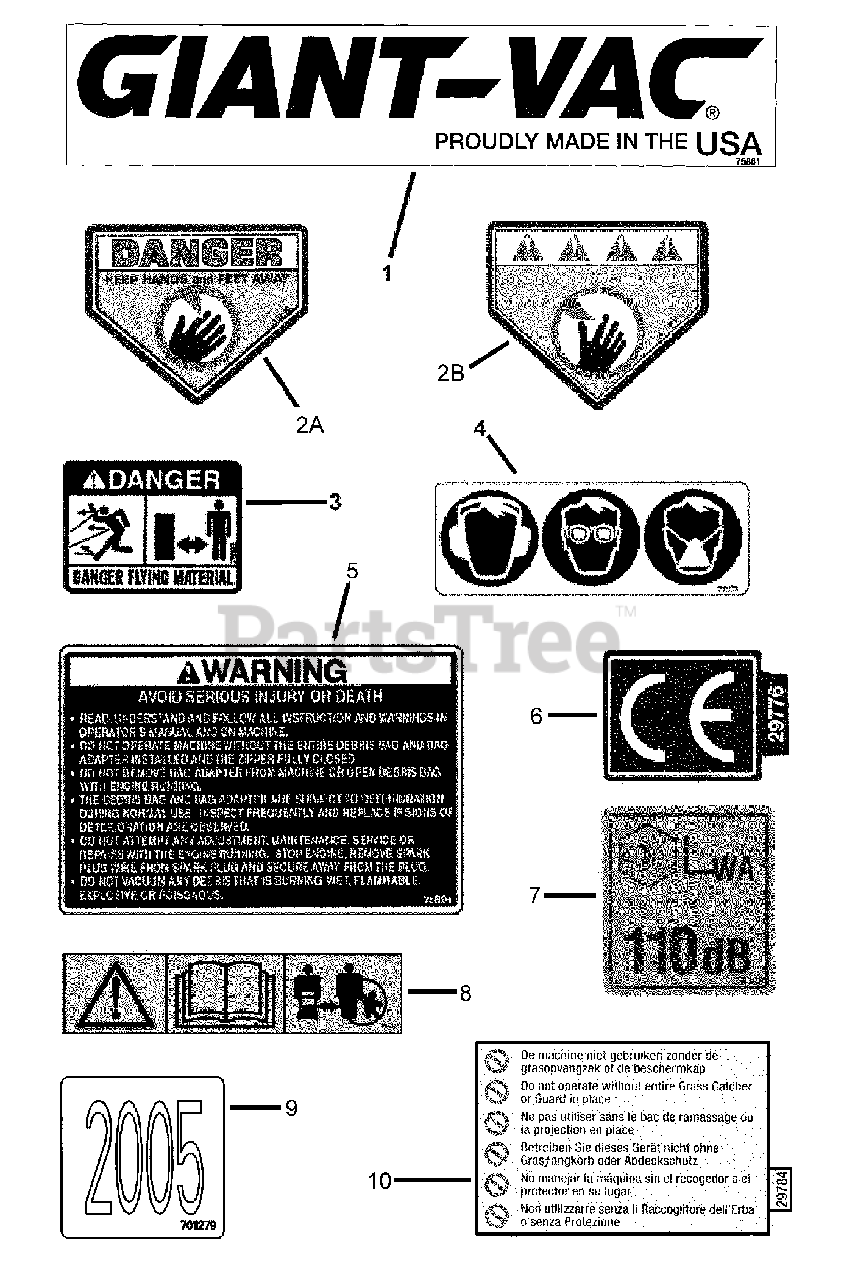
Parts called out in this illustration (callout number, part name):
1	DECAL, GIANT VAC Logo
2A	DECAL, Danger, Cut Finger
2B	DECAL, WARNING
3	DECAL, Thrown Objects
4	DECAL, Personal Protection
5	DECAL, Warning, Vacuum
6	DECAL, Euro Community (CE)
7	DECAL, SOUND 110
8	DECAL, Caution Symbols
9	DECAL, 2005 YEAR OF MFG. (No longer available)
10	DECAL, DK/Chute INT'L Warning
